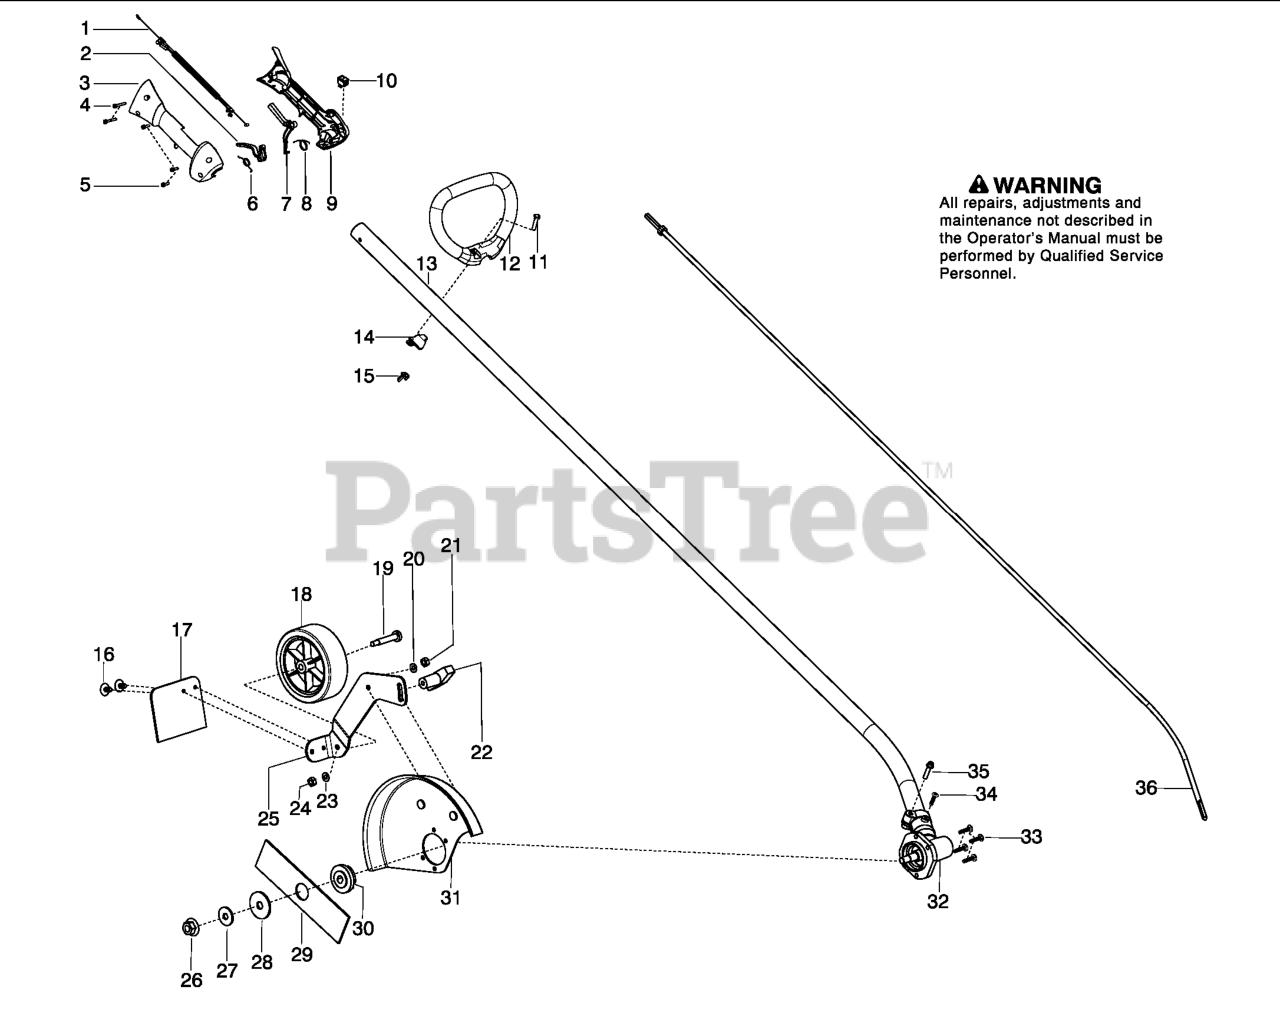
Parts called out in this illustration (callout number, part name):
1	Assy-Cable/Wire Harness
2	TRIGGER THROTTLE
3	HOUSING-THROTTLE RH
5	SCREW M4 X 1.75 PT 16MM
6	SPRING TRIGGER
7	THROTTLE LOCKOUT
8	SPRING LOCKOUT
9	HSG THROTTLE LH
10	KIT SWITCH
11	BOLT, TYPE 2
13	KIT DRIVESHAFT EDGER
14	CLAMP ASSIST HANDLE
15	WINGNUT, TYPE 2
16	FASTENER MUD FLAP
17	KIT MUD FLAP
18	WHEEL-4"(FRONT)(RUBBER)
19	BOLT-SHOULDER AXLE
25	WHEEL BRKT ADJ
26	NUT-FLANGE (LH)
27	WASHER BELLVILLE
28	WASHER-FLAT.
31	KIT - EDGER GUARD
32	KIT GEARBOX EDGER HUSQ
33	SCR 10-24 MS LDK PAN PH
34	SCREW 8-16 X 9/16 (PLAS
35	SCREW - CARB. ADAPTOR
36	Flexshaft
